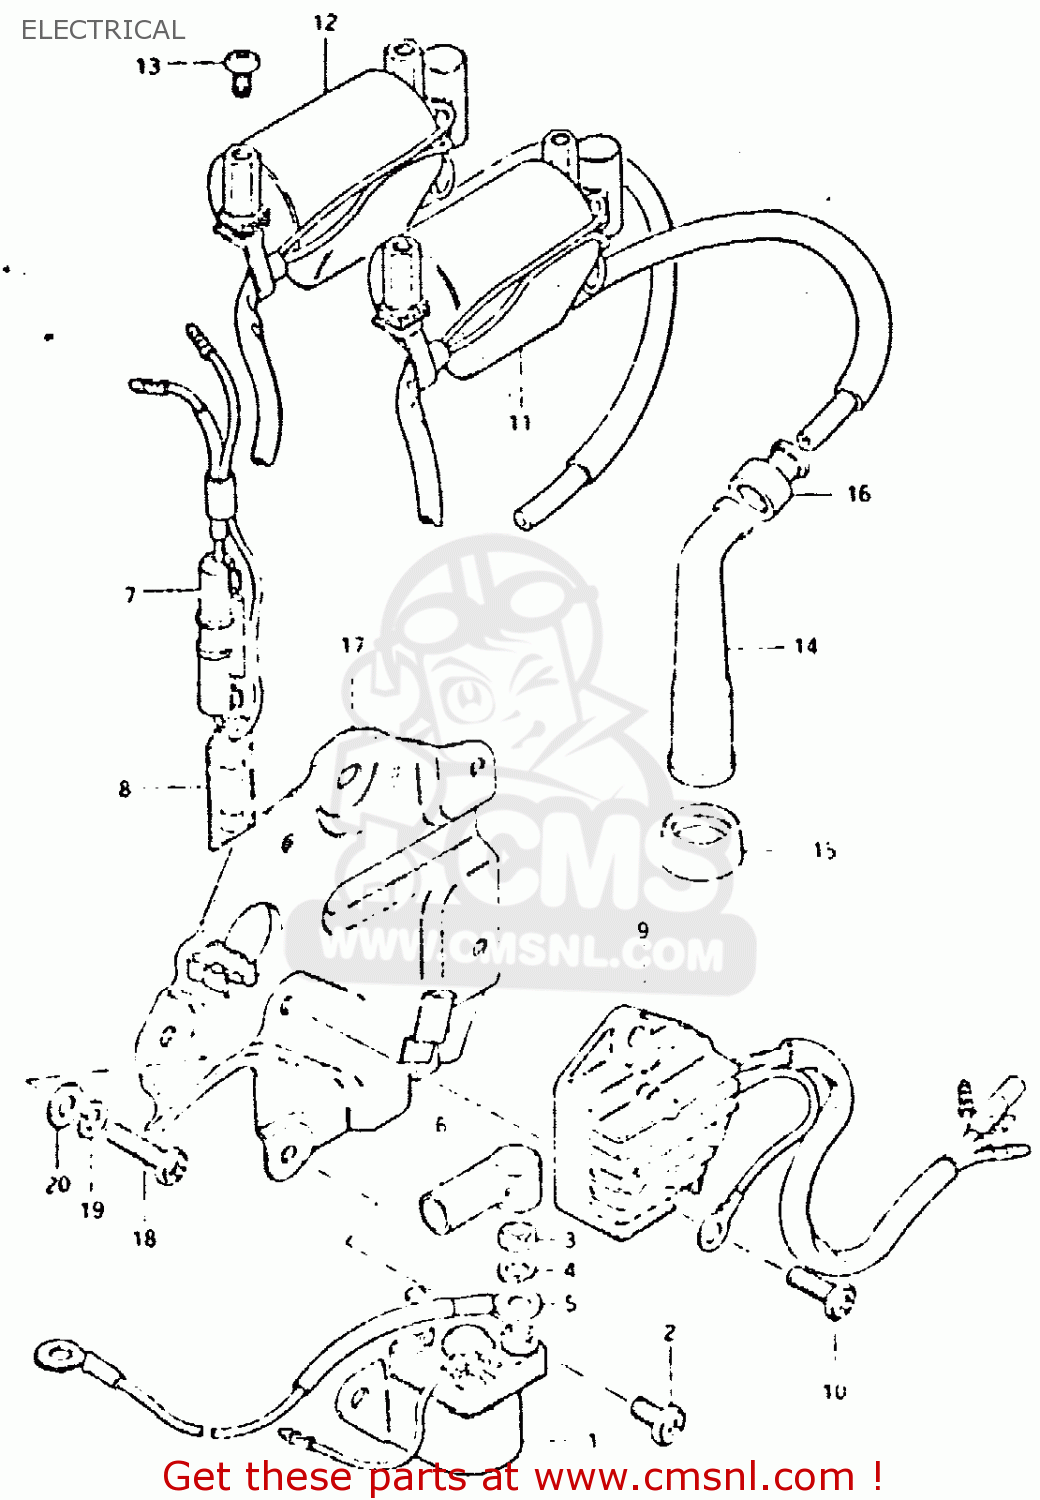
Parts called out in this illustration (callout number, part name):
1	RELAY ASSY,STARTING MOTOR
2	SCREW
3	NUT 6MM
4	LOCK WASHER
5	CORD,BATTERY MINUS
6	CAP,STARTER RELAY
7	BOX ASSEMBLY,FUSE
8	FUSE(15A)
9	RECTIFIER ASSEMBLY
10	SCREW
11	COIL ASSEMBLY,IGNITION
12	COIL ASSEMBLY,IGNITION
13	SCREW
14	CAP ASSY,SPARK PLUG
15	SEAL,SPARK PLUG
16	SEAL,SPARK PLU
17	PLATE,ELECTRIC PARTS H
18	SCREW
19	LOCK WASHER
20	WASHER
